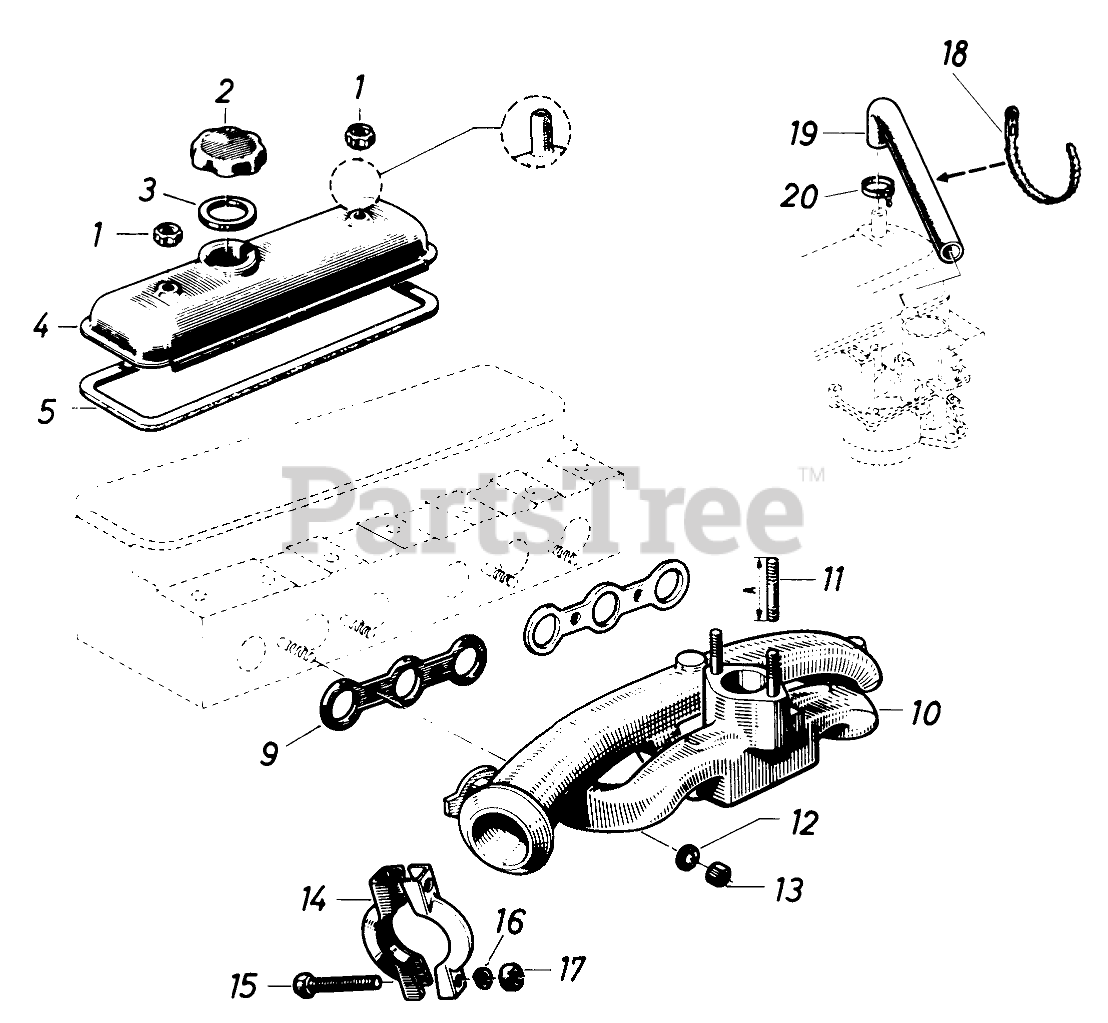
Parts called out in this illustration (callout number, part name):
2	COVER
3	Gasket
4	Valve Cover
5	Gasket
9	Gasket
10	Intake Manifold
12	Lock Washer
14	Clamp
15	Screw
16	Lock Washer
18	Fastening Strap
19	Intake Hose
20	Clamp
